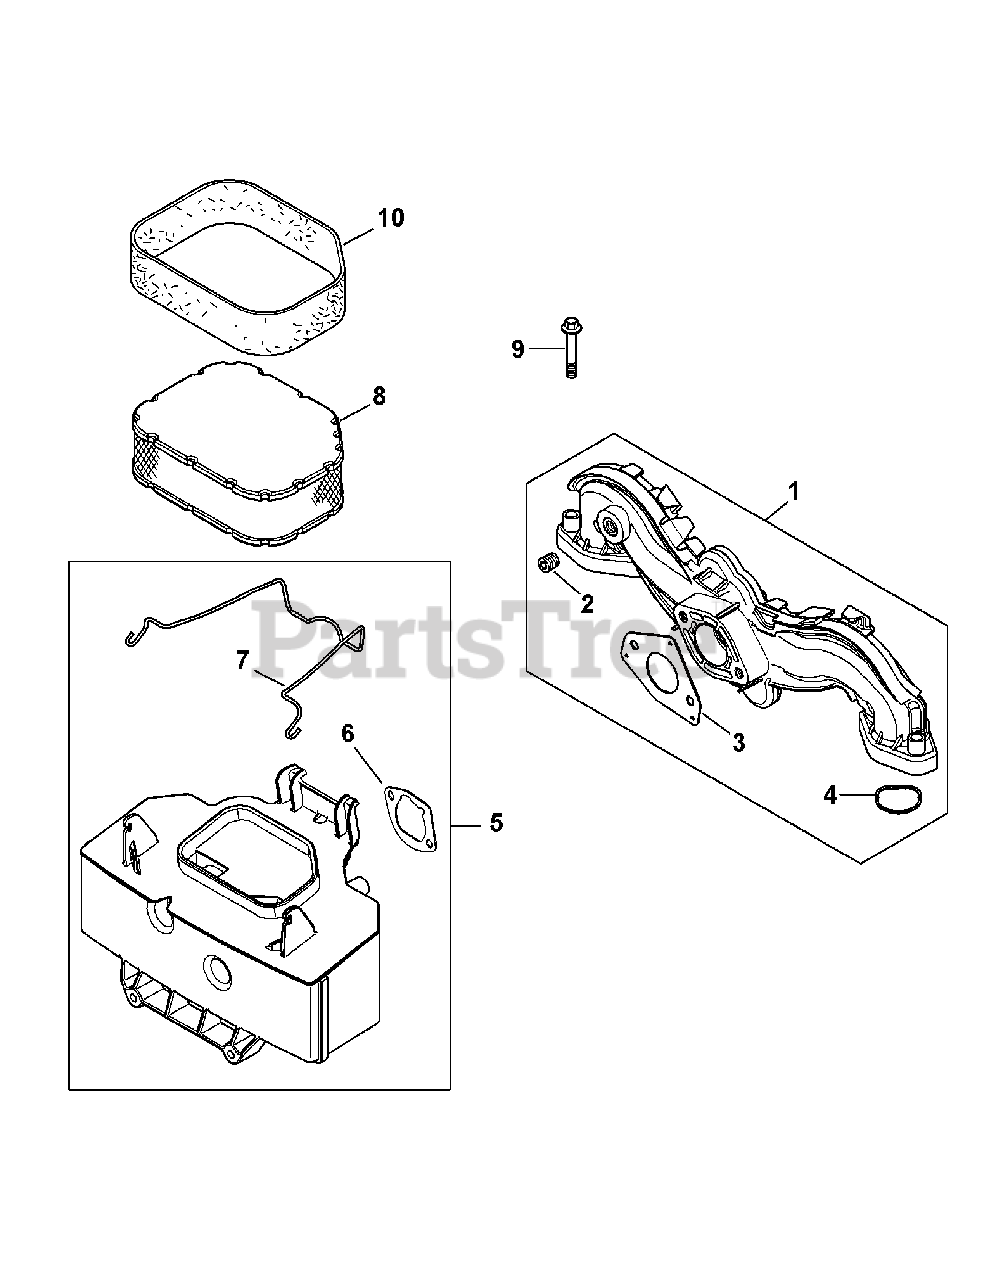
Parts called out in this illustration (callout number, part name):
1	Intake Manifold Kit (Inc. 2-4)
2	Carburetor Gasket
3	Intake Port O-Ring
4	Ctsk. Pipe Plug, 1/8
5	Air Cleaner Base Kit (Inc. 5 & 6)
6	Air Cleaner Base Gasket
7	Air Cleaner Element Latch
8	Air Filter Element with Pre-Cleaner
9	Flg. Screw, M6 X 1.0 X 40
10	Pre-Cleaner Element
